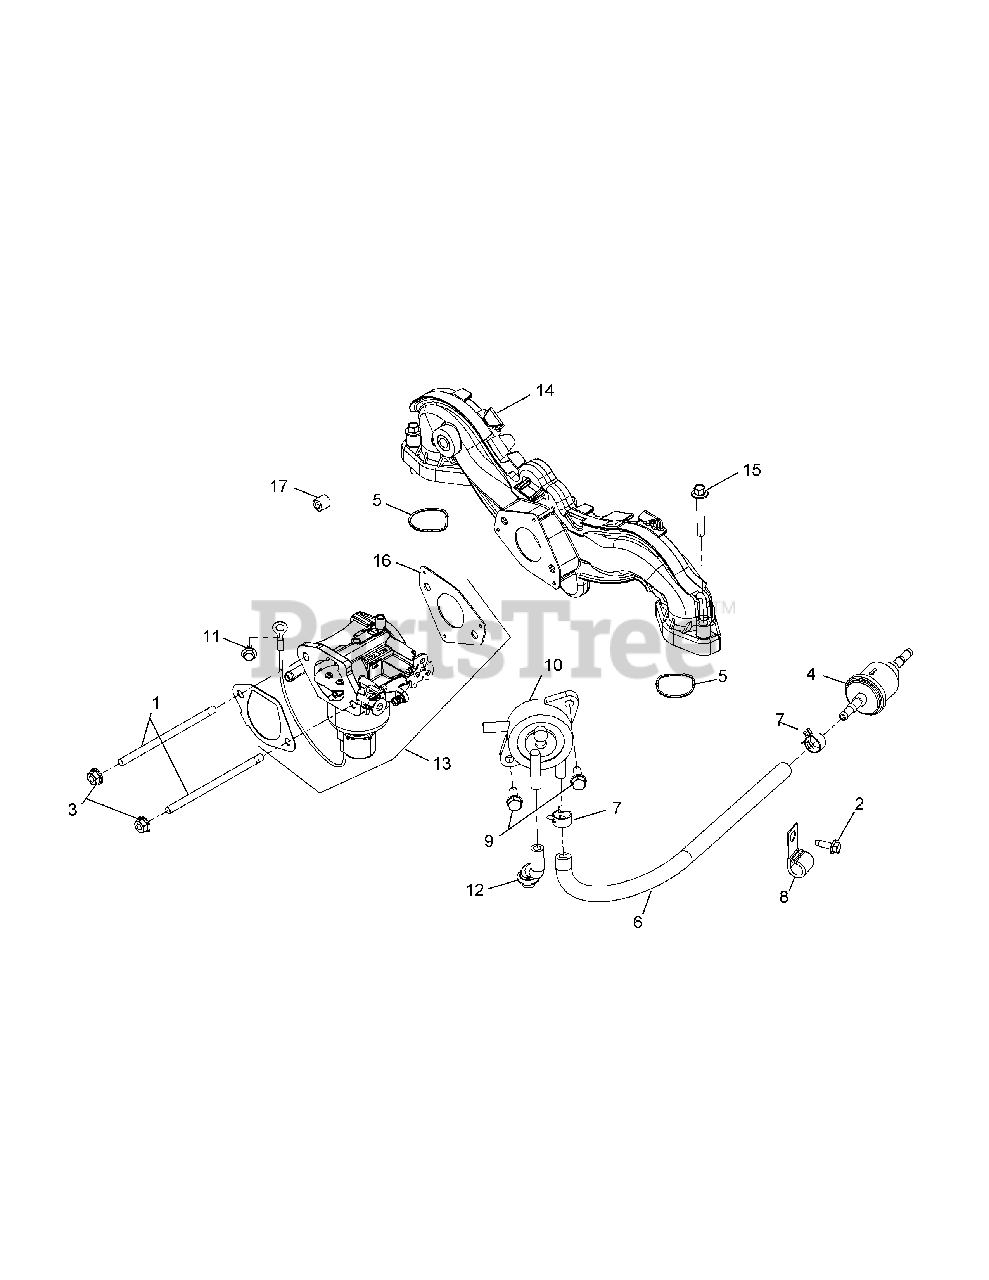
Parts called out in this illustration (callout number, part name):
2	Thread Forming Screw
3	Flange Nut, M6 x 1.0
5	Intake Port O-Ring
6	Fuel Line, 24"
7	Spring Hose Clamp
9	Tap Screw, M6 x 1.7 x 18
11	Thread Forming Screw
12	Pulse Pump Hose
13	Carburator Kit
14	Intake Manifold Kit
15	Flange Screw, M6 x 1.0 x 40
16	Carburetor Gasket
17	Pipe Plug, 1/8
